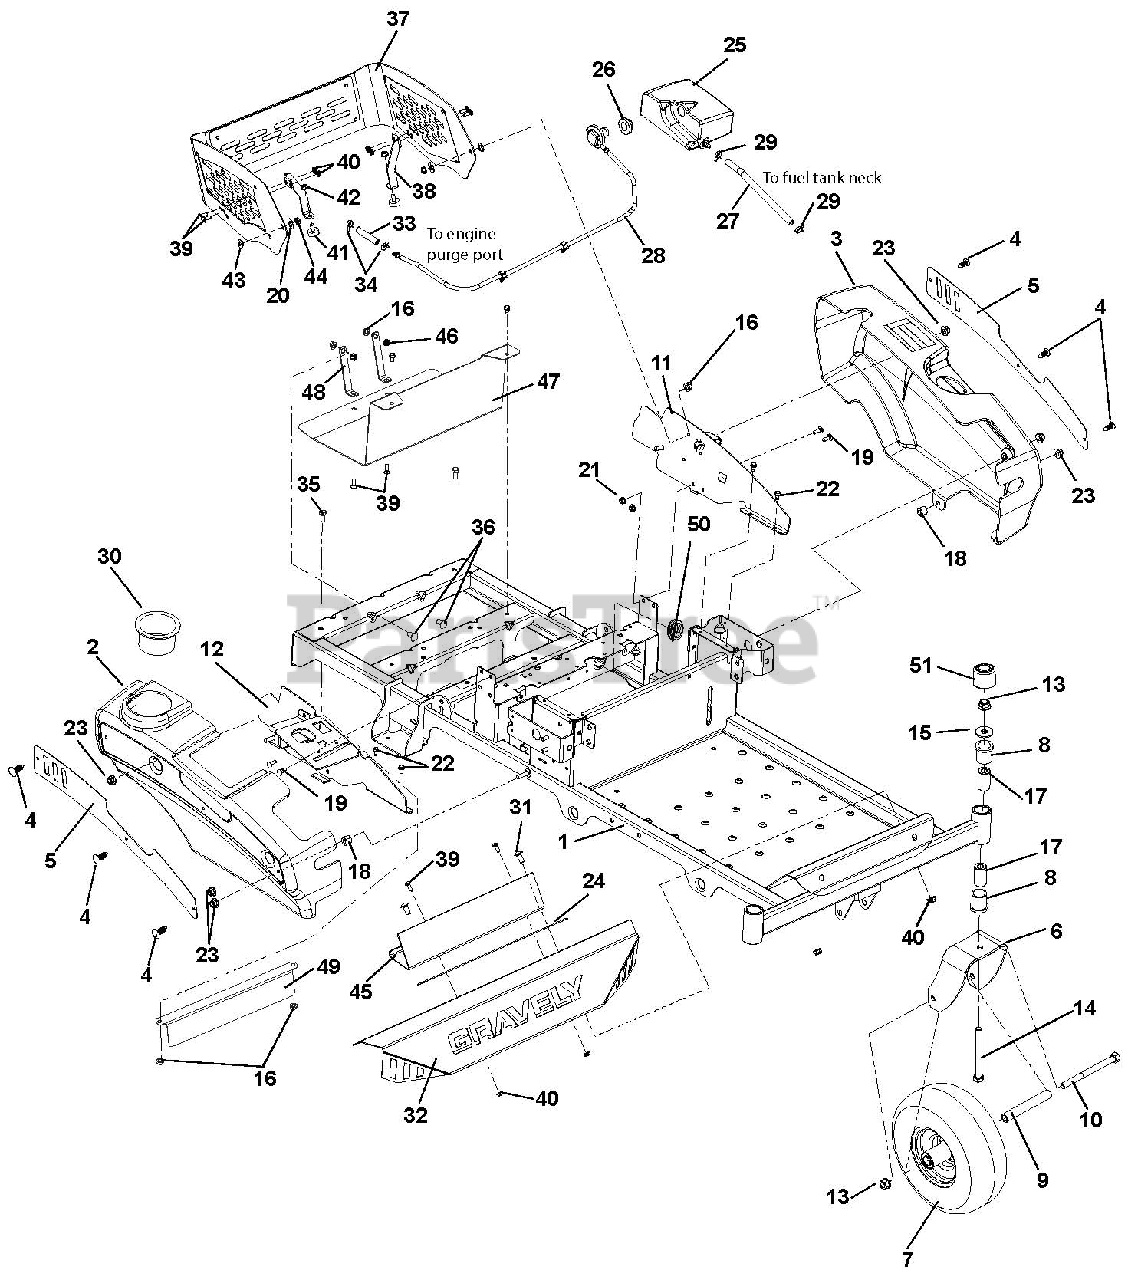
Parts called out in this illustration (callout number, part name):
1	KIT, ZOOM/ZT FRAME W/ DECALS
2	FENDER, RH
3	FENDER, LH
4	RIVET, .25 NYLON PANEL
5	PLATE, FENDER ZT
6	WMT, CASTER FORK
7	ASM, WHL/TIRE 11X4.00-5
7	TIRE, 11X4-5 TURF TREAD
7	TUBE 11 X4.0-5 TR87
8	BSHG-FLG 1.00X1.25X1.50X1.50
9	SPACER, ROLLED WHEEL
10	@BLT-HEX .50-13X6.50 GR5 YWZC
11	WLDMT, RH FENDER MOUNT
12	WLDMT, RH FENDER MOUNT
13	@NUT-LK-TOP-FLG .50-13 YWZC
14	@BLT-HEX .50-13X5.00 GR5 YWZC
15	WSHR-FL-STL.511X1.441X.125 YWZ
16	@NUT-LK-TOP-FLG .38-16 YWZC
17	SPACER, CASTER .50X1.00X1.84
18	BSHG-SLV .391X.688X.52 PM
19	@BLT-RDHDSQNK .25-20X.75 G5YZ
20	@NUT-LK-NYL-FLG .25-20 YWZC
21	SCR-TAP .25-20X.50 HWH TR YWZ
22	SCR-TAP .25-20X.50 HWH TR YWZ
23	@NUT-LK-NYL-FLG .31-18 YWZC
24	GRIP, ADHESIVE (1" X 16" BLK)
25	EXPANSION TANK SUB ASSY
26	GROMMET, REMOTE VENT NITRILE
27	HOSE, .25 LOW-PERM BULK GAS
28	ASM, FUEL VENT - ZOOM/ZT
29	CLAMP, FUEL LINE
30	CUPHOLDER, SNAP-IN 3.75OD
31	BLT-RDHDSQNK .50-13X7.00
32	PLATE, FOOT ZT
33	HOSE, .188 LOW-PERM BULK GAS
34	CLAMP-HOSE, SPRING .188
35	@BLT-HEX .38-16X1.00 GR5 YWZC
36	@BLT-RDHDSQNK .38-16X1.00 G5YZ
37	ASSEMBLY, ENGINE WRAP ZT
38	HOSE, .25 LOW-PERM BULK GAS
39	@BLT-RDHDSQNK .25-20X.50 G5YZ
40	NUT-LK-CTR-FLG .25-20 YWZC
41	BUMPER, RUBBER
42	@NUT-SPNLK-FLG .312-18 YWZC
43	BSHG-FLG .325X.499X.3X.875
44	@NUT-LK-CTR-FLG .31-18 YZ GR F
45	PLATE, BACK FOOT-PLATE
46	@NUT-LK-TOP-FLG .25-20 YWZC
47	GUARD, HEAT SHIELD (ZOOM/ZT)
48	STRAP, HEAT SHIELD (ZOOM/ZT)
49	GUARD, HOT SURFACE (ZOOM/ZT)
50	GROMMET 1.0ID X 1.38 OD
51	CAP, DUST
